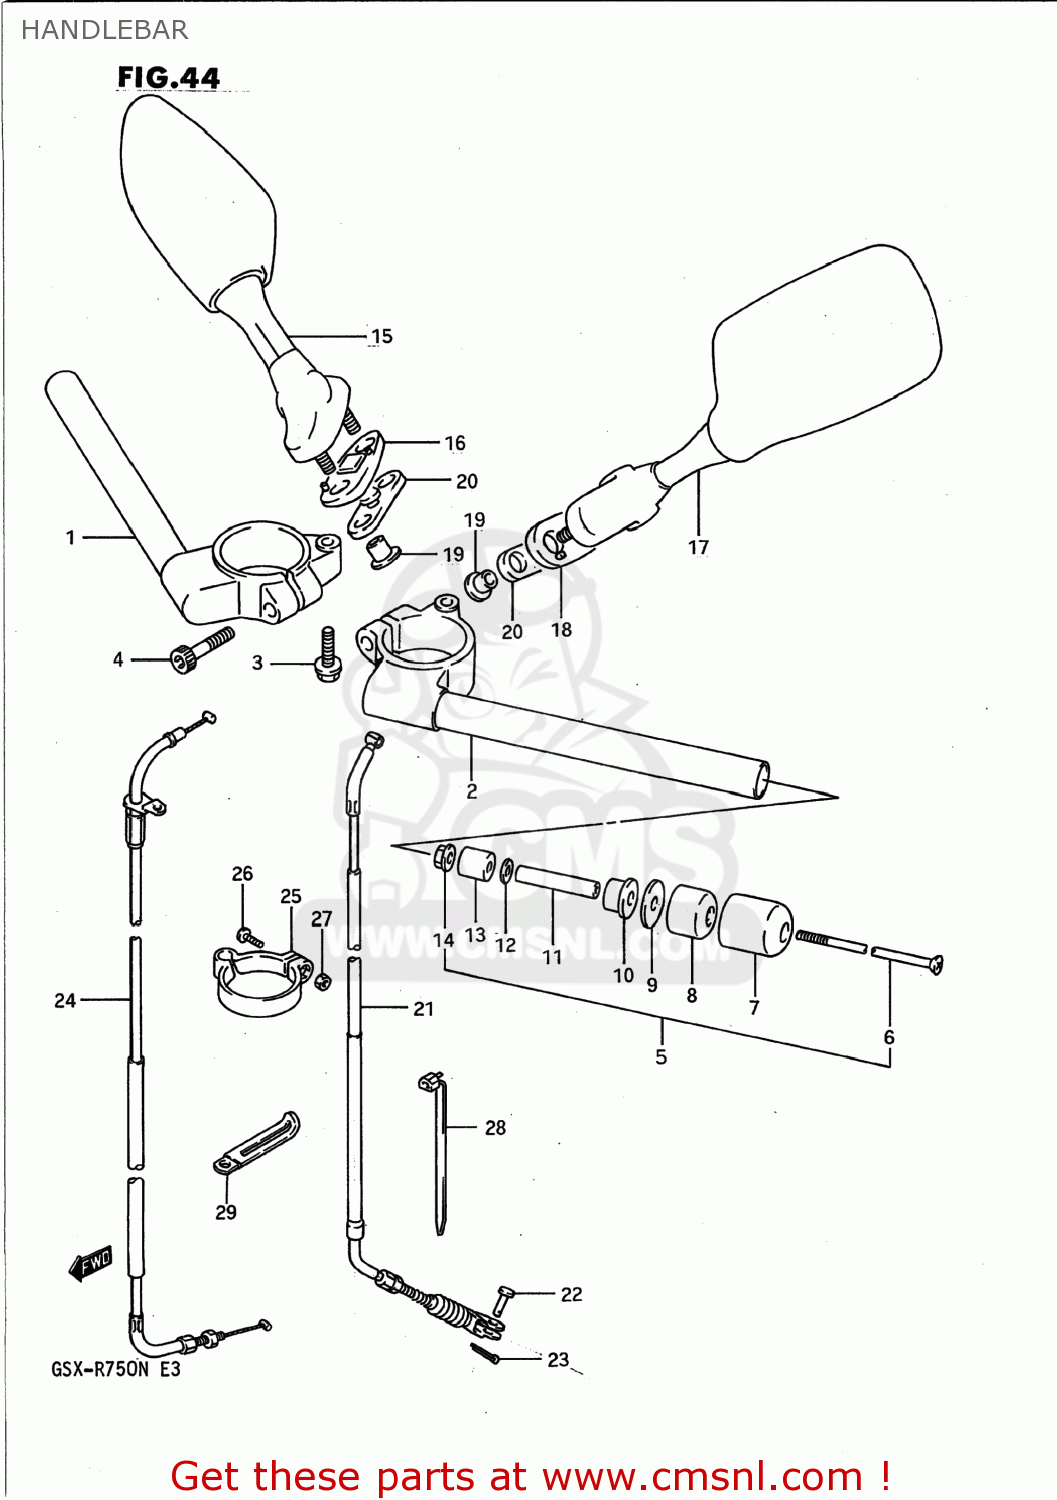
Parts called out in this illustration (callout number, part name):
1	HANDLEBAR,R
2	HANDLEBAR,L
3	BOLT 6X20
4	BOLT 8X35
5	BALANCER SET,HANDLEBAR
6	SCREW(6X127)
7	CAP,BALANCER
8	BALANCER,HANDLEBAR
9	SPACER,BALANCER
10	EXPANDER,HANDLE BALANCER
11	SPACER,EXPANDER
12	WASHER
13	EXPANDER,HANDLE BALANCER
14	NUT
15	MIRROR ASSY,RR VIEW,R
16	GASKET,RR VIEW MIRROR,R (NAS)
17	MIRROR ASSY,RR VIEW,L
18	GASKET,RR VIEW MIRROR,L (NAS)
19	NUT,RR VIEW MIRROR
20	CUSHION,RR VIEW MIRRORR
21	CABLE ASSY,CLUTCH
22	PIN(L:15)
23	PIN
24	CABLE ASSY,THROTTLE
25	CLAMP,CLUTCH CABLE NO
26	SCREW
27	NUT ,5MM
28	CLAMP(L:235)
29	CLAMP
